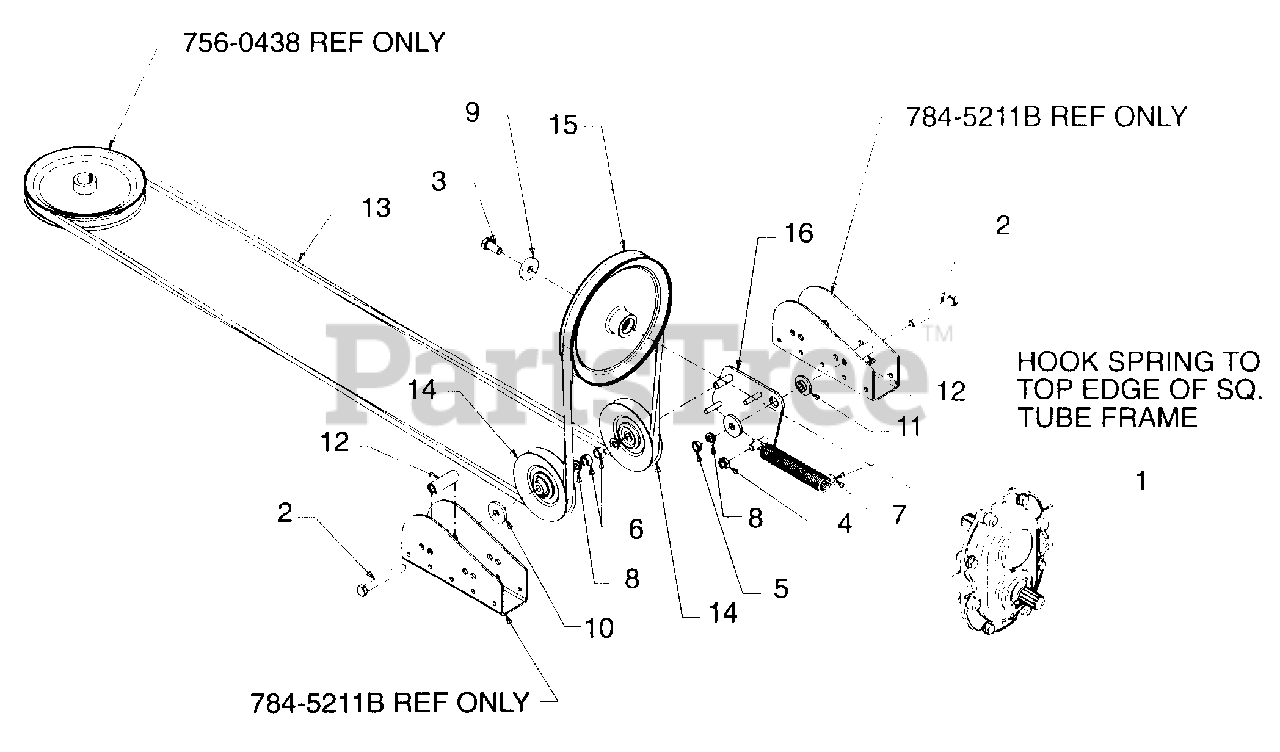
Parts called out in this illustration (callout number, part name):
1	BOX ASM:SPKT
2	HHCS:3/8-16:3.00:GR8:STD
3	HHCS:3/8-24:.875:GR8:STD
4	NUT:JAM:3/8-24:INS LOCK
5	HEX CENT L-JAM NUT 3/8-16
6	NUT:3/8-16:GRB:HX
7	SPR:EXTN:.87 DIA X 6.00 LG
8	WASH:LOCK:3/8:REGULAR DUTY
9	FL-WASH .406 ID X 1.25 OD
10	FLAT WASHER .406 ID X 1 1/4 OD
11	SHLD SPACER .625 ID X .169
12	SPACER .32 ID X .625 OD X 1.74
13	BELT:V TYP:A SECT X 126.0 POLY
14	V-BELT IDLER-.38 ID X 4.0 DIA
15	PUL:DR:7.00 DIA
